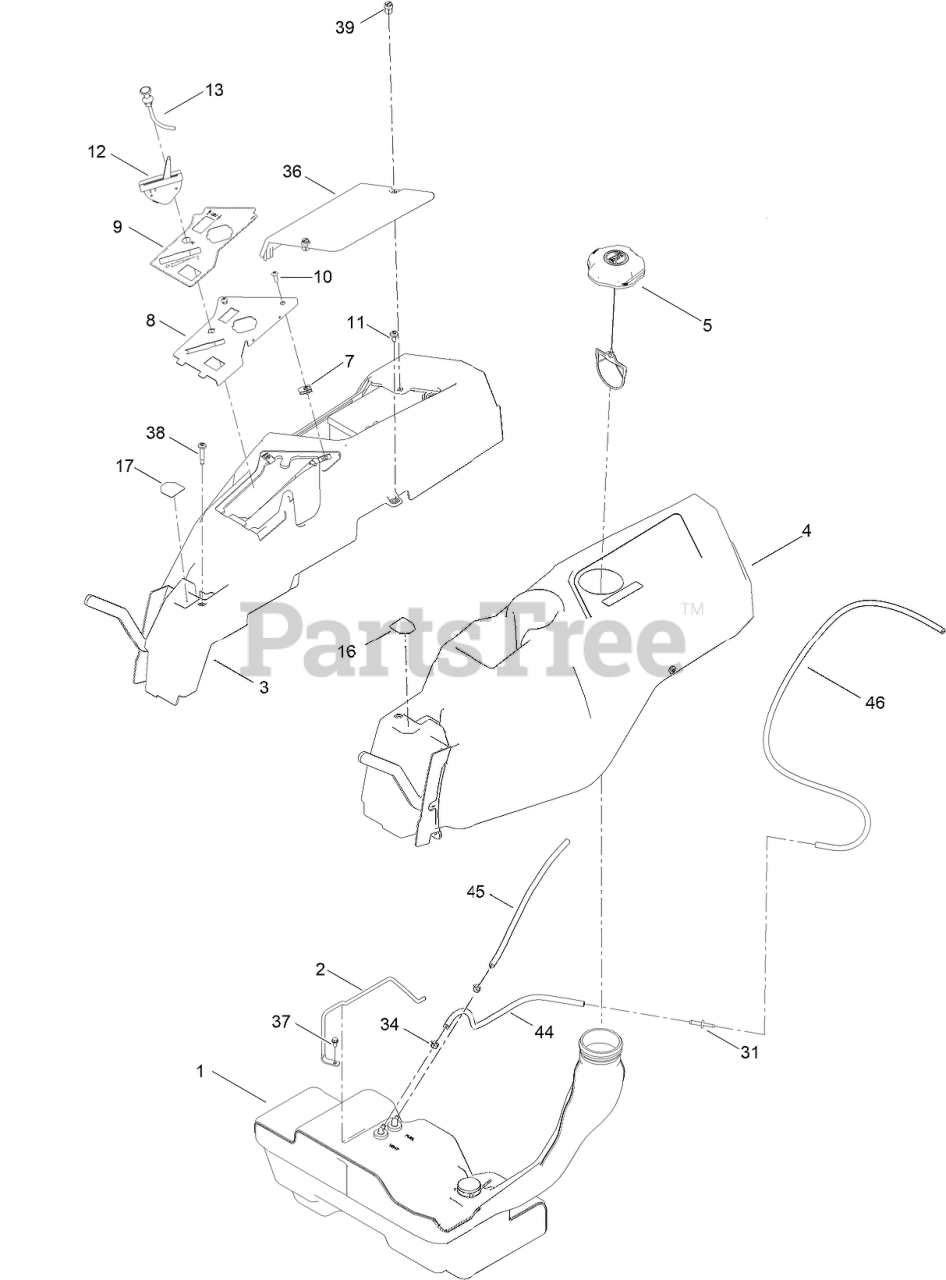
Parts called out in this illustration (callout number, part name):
1	FUEL TANK ASM
2	ROD-HOLD DOWN
3	POD-RH
4	POD-LH
5	CAP-FUEL, RATCHETING
8	PANEL-CONTROL
9	DECAL-PANEL, CONTROL
10	SCREW-PRH
11	SCREW-SHOULDER
12	CABLE-THROTTLE
13	CABLE-CHOKE
16	DECAL-LEVER, CONTROL (LH)
17	DECAL-LEVER, CONTROL (RH)
31	ADAPTOR-ORIFICE
34	CLAMP-HOSE
36	COVER-BATTERY
37	SCREW-HWH
38	SCREW-SHOULDER
39	FASTENER
44	HOSE-FUEL
45	HOSE-VENT
46	HOSE-FUEL
